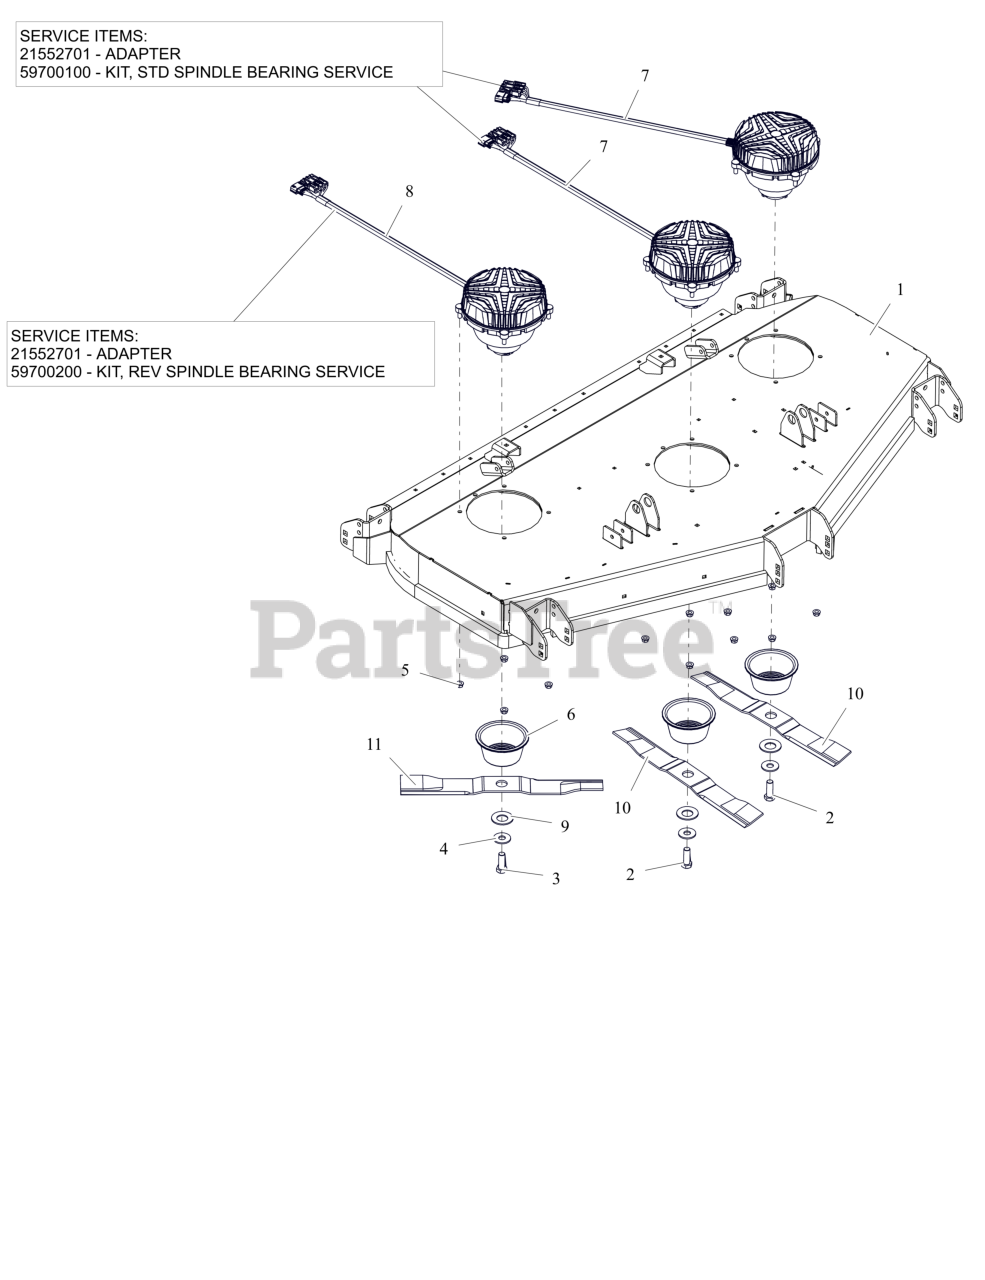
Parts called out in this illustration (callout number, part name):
1	KIT,DECK 60 RD W/DECALS-A
2	BLT, HEX .62-18X1.75 G8 ZCC
3	BLT, HEX 0.625-11X1.75 GR8 ZCC LH
4	WSHR, HRDN 0.687X1.75X0.134 HRD
5	NUT-LK-CTR-FLG .375-16 GF ZCC
6	GUARD, SPINDLE LOWER
7	MOTOR, SPINDLE-CW
7	ADAPTER
7	KIT,STD SPINDLE BEARING SERVICE
8	MOTOR, DECK SPINDLE -CCW
8	ADAPTER
8	KIT,REV SPINDLE BEARING SERVICE
9	WSHR, BLVL - .56X28.5X3 PHOS.COAT
10	BLADE, MOWER 20.5"
11	BLADE, MOWER - 20.5" EFF CCW
